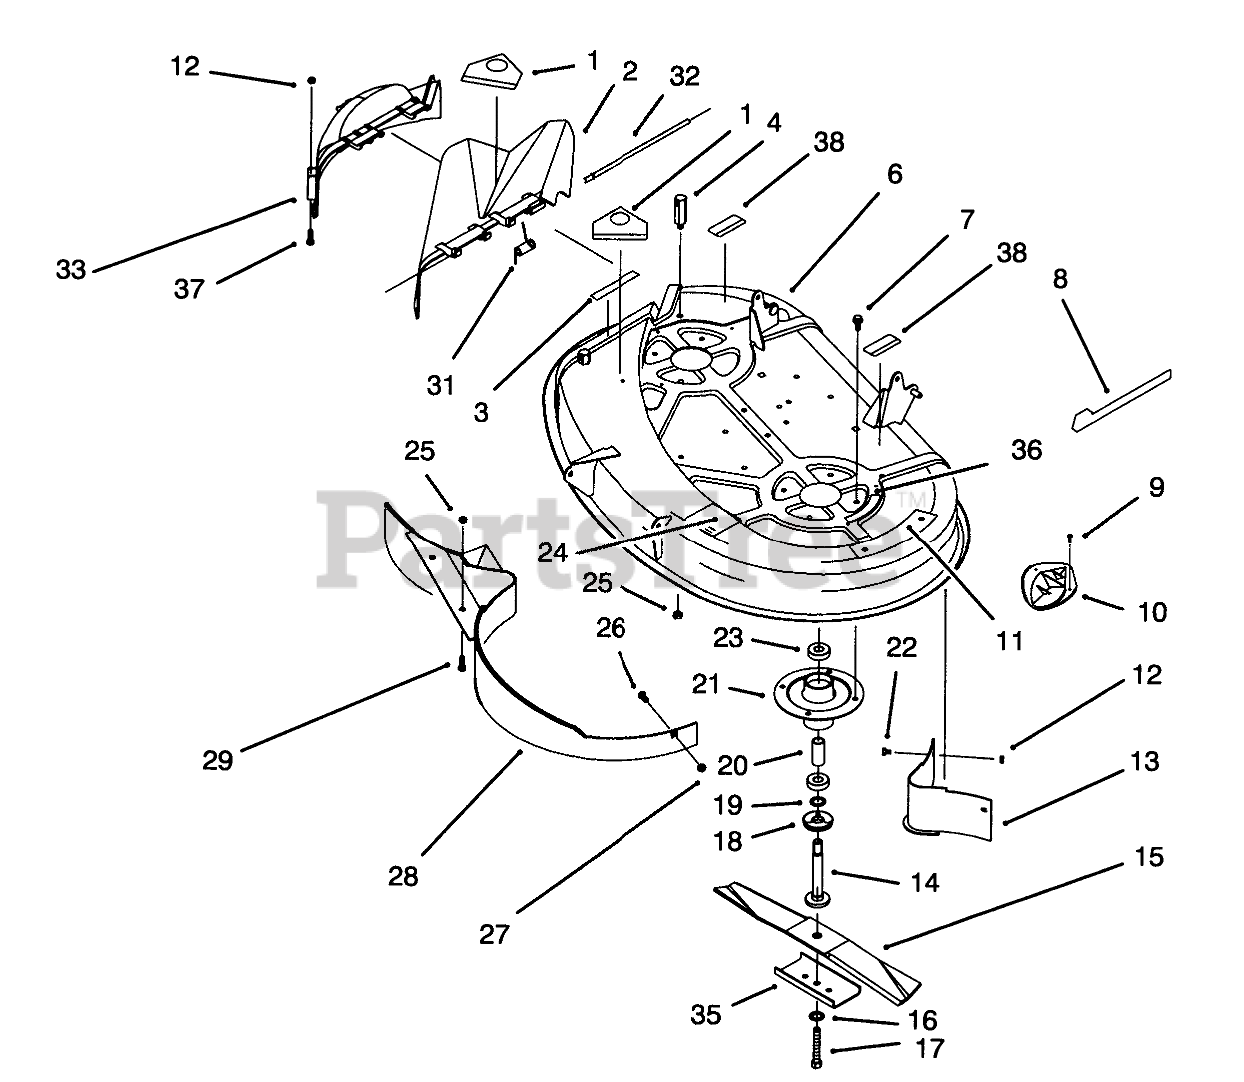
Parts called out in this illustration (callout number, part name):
1	DECAL-DANGER
2	Deflector Ass-y (Incl. Ref. #1)
3	DECAL-DANGER, DEFLECTOR
4	REAR PIVOT POST (PLTD)
6	Deck-38"
7	SCREW-TAPTITE
8	DECAL-RECYCLER DECK 38"
9	SCREW-PPH
10	PLATE-KICKER
11	DECAL-DANGER
12	NUT-LOCK, NI
13	Baffle-Rear
14	SHAFT-SPINDLE
15	Blade
16	WASHER-BELLEVILLE
17	SCREW-HH
18	SHIELD-BEARING
19	SPACER
20	SPACER
21	HOUSING-SPINDLE
22	SCREW-HH
23	BEARING-BALL
24	Decal-Routing
25	NUT-LOCK, NI
26	BOLT-CARR
27	NUT-LOCK, NI
28	Baffle-38"
29	SCREW-HH
31	SPRING
32	ROD-HINGE DEFLECTOR
33	COVER-RECYCLER
35	Stiffener
36	DECAL-DANGER, SHIELD
37	SCREW-HH
38	DECAL-WARNING
